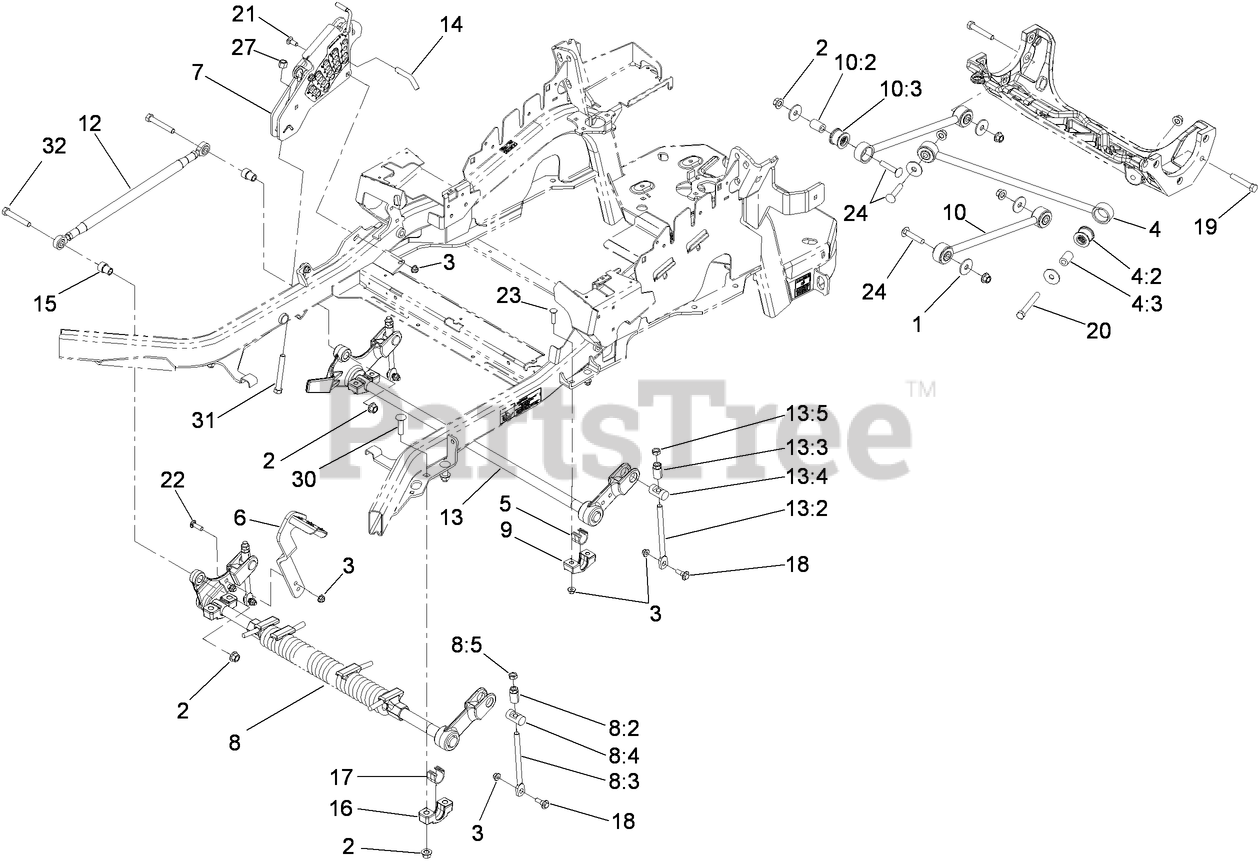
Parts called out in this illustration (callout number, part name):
1	WASHER-THRUST
2	NUT-LOCK
3	NUT-HF, NI
4	PANHARD ROD ASM
4:2	BUSHING-SUSPENSION, RUBBER
4:3	SPACER
5	BEARING-CROSS SHAFT, REAR
6	PEDAL-FOOT
7	HOC ASM
8	FRONT DECK LIFT ASM
8:2	ADJUSTER-LIFT, DECK
8:3	LINK-ADJUSTER, DECK LIFT
8:4	TRUNNION
8:5	NUT-JAM
9	SUPPORT-BEARING, CROSS SHAFT
10	DECK STRUT ASM
10:2	BUSHING-SUSPENSION, RUBBER
10:3	SPACER
12	SIDE LINK ASM
13	REAR DECK LIFT ASM
13:2	LINK-ADJUSTER, DECK LIFT
13:3	ADJUSTER-LIFT, DECK
13:4	TRUNNION
13:5	NUT-JAM
14	PIN-HOC
15	BUSHING-FLANGE
16	SUPPORT-CROSS SHAFT, BEARING
17	BEARING-CROSS SHAFT, FRONT
18	SCREW-SHOULDER, HHF
19	SCREW-HH
20	SCREW-HH
21	BOLT-CARR
22	SCREW-CARR
23	SCREW-CARR
24	SCREW-CARR
27	NUT-LOCK, NI
30	SCREW-CARR, SHORT NECK
31	BOLT-TAP
32	SCREW-HH
